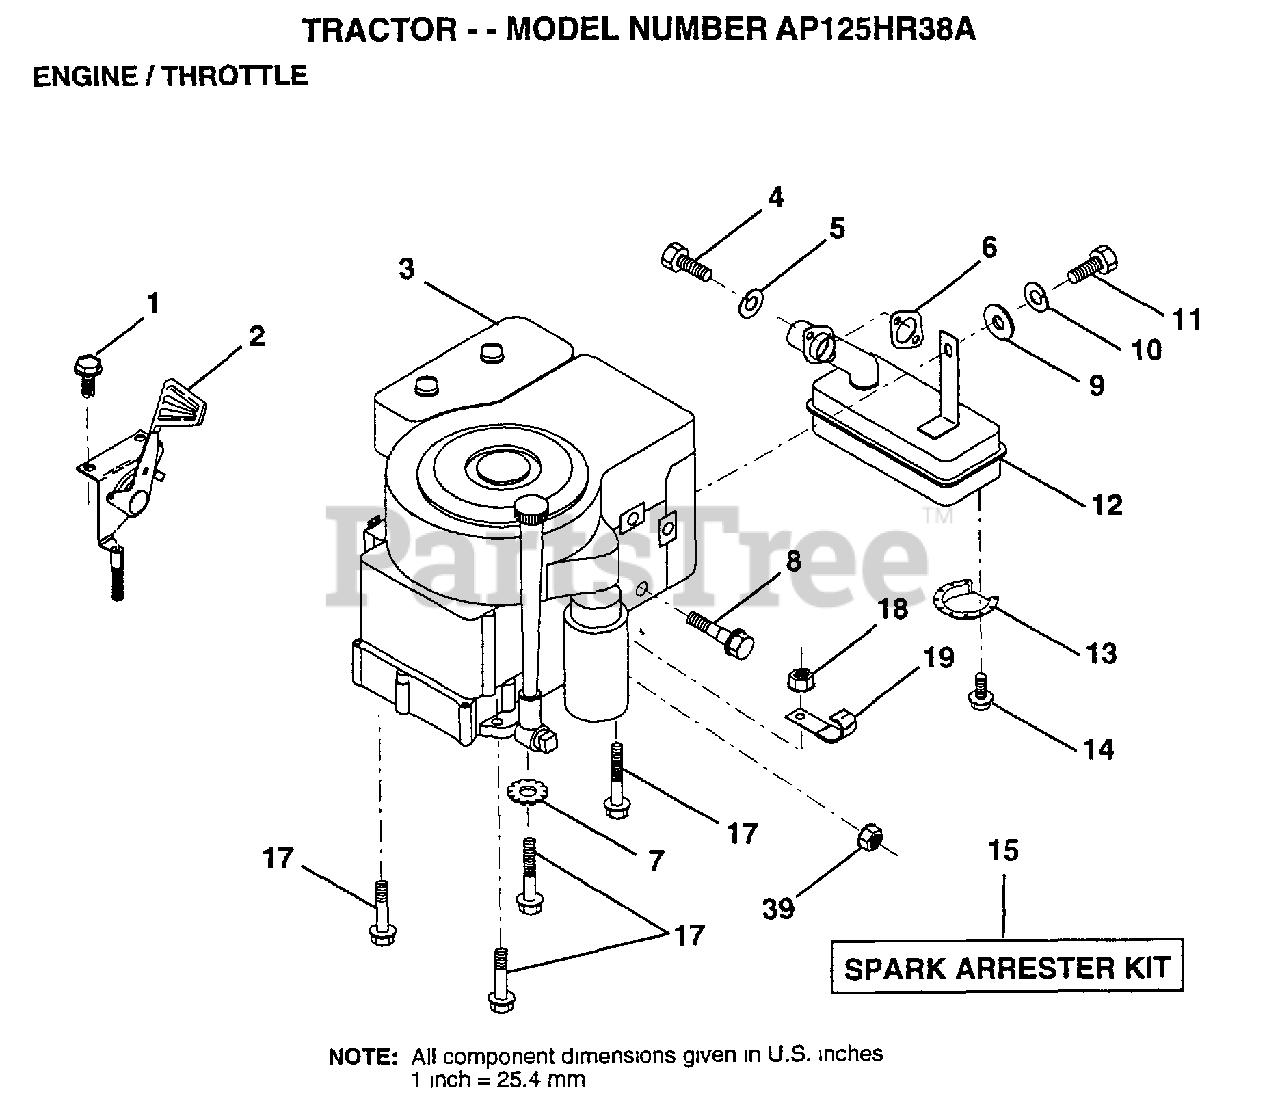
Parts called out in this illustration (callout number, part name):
1	SCREW.1/4-20X1/2
2	"CONTROL,THROTTLE"
4	SCREW
5	LOCKWASHER
7	LOCKWASHER
8	BOLT T
10	LOCKWASHER
12	MUFFLER
13	DEFLECTOR.222573
17	SCREW LT
18	NUT
19	CLIP T
39	NUT
